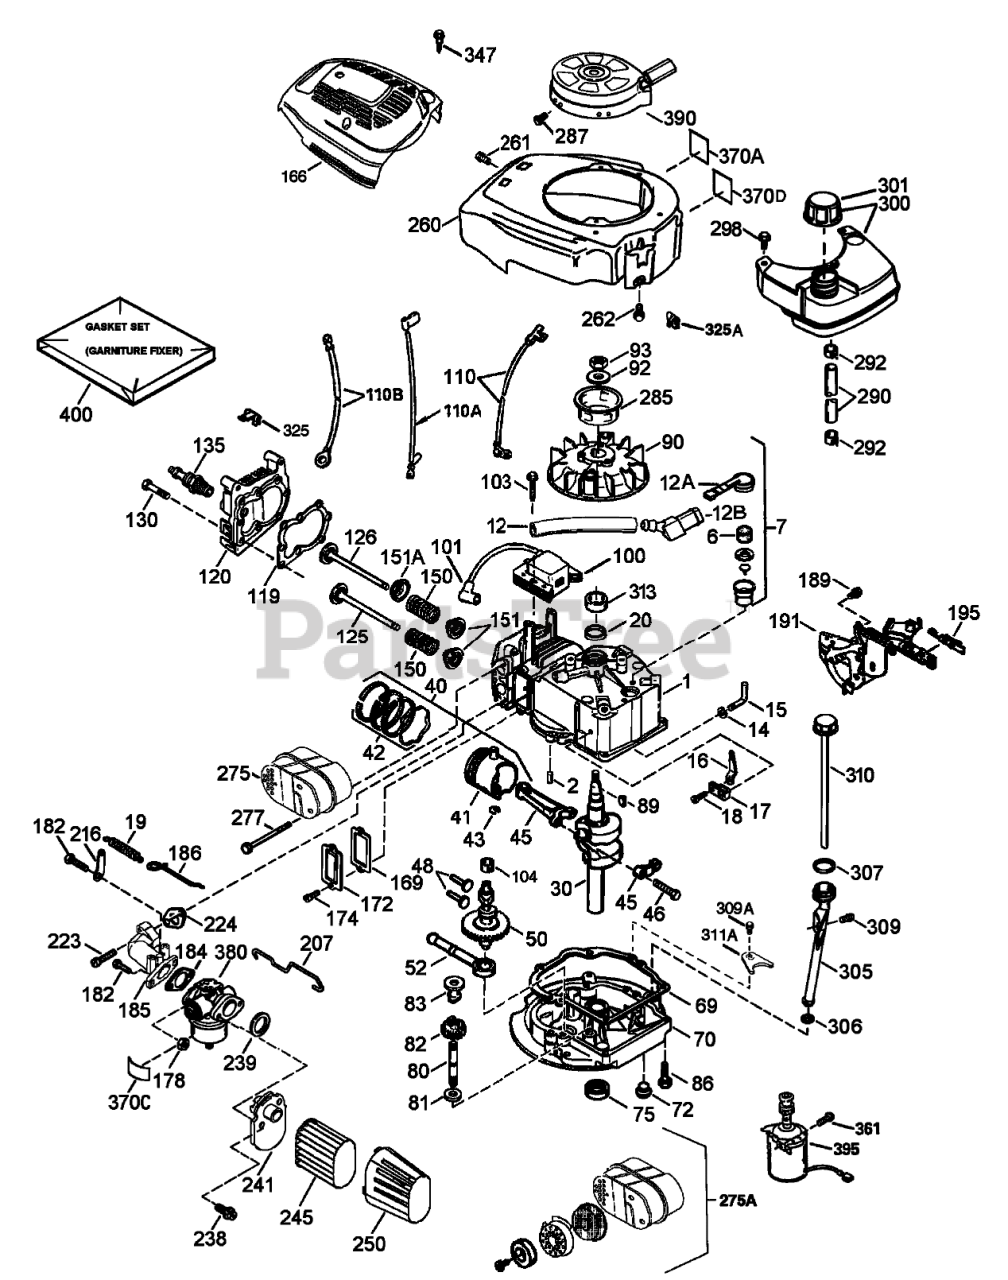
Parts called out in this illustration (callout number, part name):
1	Cylinder ASM (Incl. Ref. #2, 20 and 150)
2	Pin-Dowel
6	Element-Breather
7	Breather ASM (Incl. Ref. #6 and 12A)
12	Tube-Breather
12A	Breather Cover and Tube (Incl. Ref. #12B)
12B	Elbow-Tube, Breather
14	Washer-Flat
15	Governor Rod (Incl. Ref. #14)
16	Lever-Governor
17	Clamp-Lever, Governor
18	Screw (T-15, 8-32 x 19/64)
19	Spring-Extension
20	Seal-Oil
30	Crankshaft
40	Piston, Pin and Ring Set (Std.)
41	Piston and Pin ASM (Std.) (Incl. Ref. #43)
42	Ring Set (STD)
43	Ring-Retaining, Piston Pin
45	Connecting Rod ASM (Incl. Ref. #46)
46	Bolt-Rod, Connecting
48	Lifter-Valve
50	Camshaft (Exhaust MCR) (Incl. Ref. #104)
52	Oil Pump ASM
69	Gasket-Flange, Mounting
70	Flange-Mounting (Incl. Ref. #72-83, 306, 309A and 311A)
72	Plug-Drain, Oil
75	Seal-Oil
80	Shaft-Governor
81	Washer-Flat
82	Governor Gear ASM (Incl. Ref. #81)
83	Spool-Governor
86	Screw (1/4-20 x 1-1/4)
89	Key-Flywheel
90	Flywheel
92	Washer-Belleville
93	Nut-Flywheel
100	Ignition-State, Solid
101	Cover-Spark Plug
103	Screw (T-15, 10-24 x 15/16)
104	Bushing-Cam
110	Wire-Ground
110A	Wire ASM
110B	Wire ASM
119	Gasket-Cylinder Head
120	Head-Cylinder
125	Exhaust Valve (1/32"" OS) (Incl. Ref. # 151)
125	Exhaust Valve (Std.) (Incl. Ref. #151)
126	Intake Valve (Std.) (Incl. Ref. #151 and 151A)
130	Screw (5/16-18x1-1/2)
135	Spark Plug-Resistor (R J19 L M)
150	Spring-Valve
151	Cap-Valve, Spring
151A	Seal-Valve, Intake
166	Shroud-Engine
169	Gasket-Cover, Valve
172	Cover-Valve
174	Screw (10-24 x 9/16)
178	Nut and Lock Washer (1/4-28)
182	Screw (1/4-28 x 7/8)
184	Gasket
185	Pipe-Intake
186	Link-Governor
189	Screw (1/4-20 x 3/8)
191	Bracket-Brake, S.E. (Incl. Ref. #195)
195	Terminal
207	Link-Throttle
216	Lever-Adjusting, R P M
223	Screw (1/4-20 x 1)
224	Gasket-Pipe, Intake
238	Screw (10-32 x 49/64)
239	Gasket-Cleaner, Air
241	Collar-Cleaner, Air
245	Filter-Cleaner, Air (Paper)
250	Cover-Cleaner, Air
260	Housing-Blower
261	Screw (10-24 x 9/16)
262	Screw (1/4-20 x 1/2)
275	Muffler
275A	Spark Arrestor Kit
277	Screw (1/4-20 x 2-9/32)
285	Cup-Starter
287	Screw (8-32 x 21/64)
290	Line-Fuel (8.62)
292	Clamp-Line, Fuel
298	Screw (10-32 x 35/64)
300	Fuel Tank ASM (Incl. Ref. #292 and 301)
